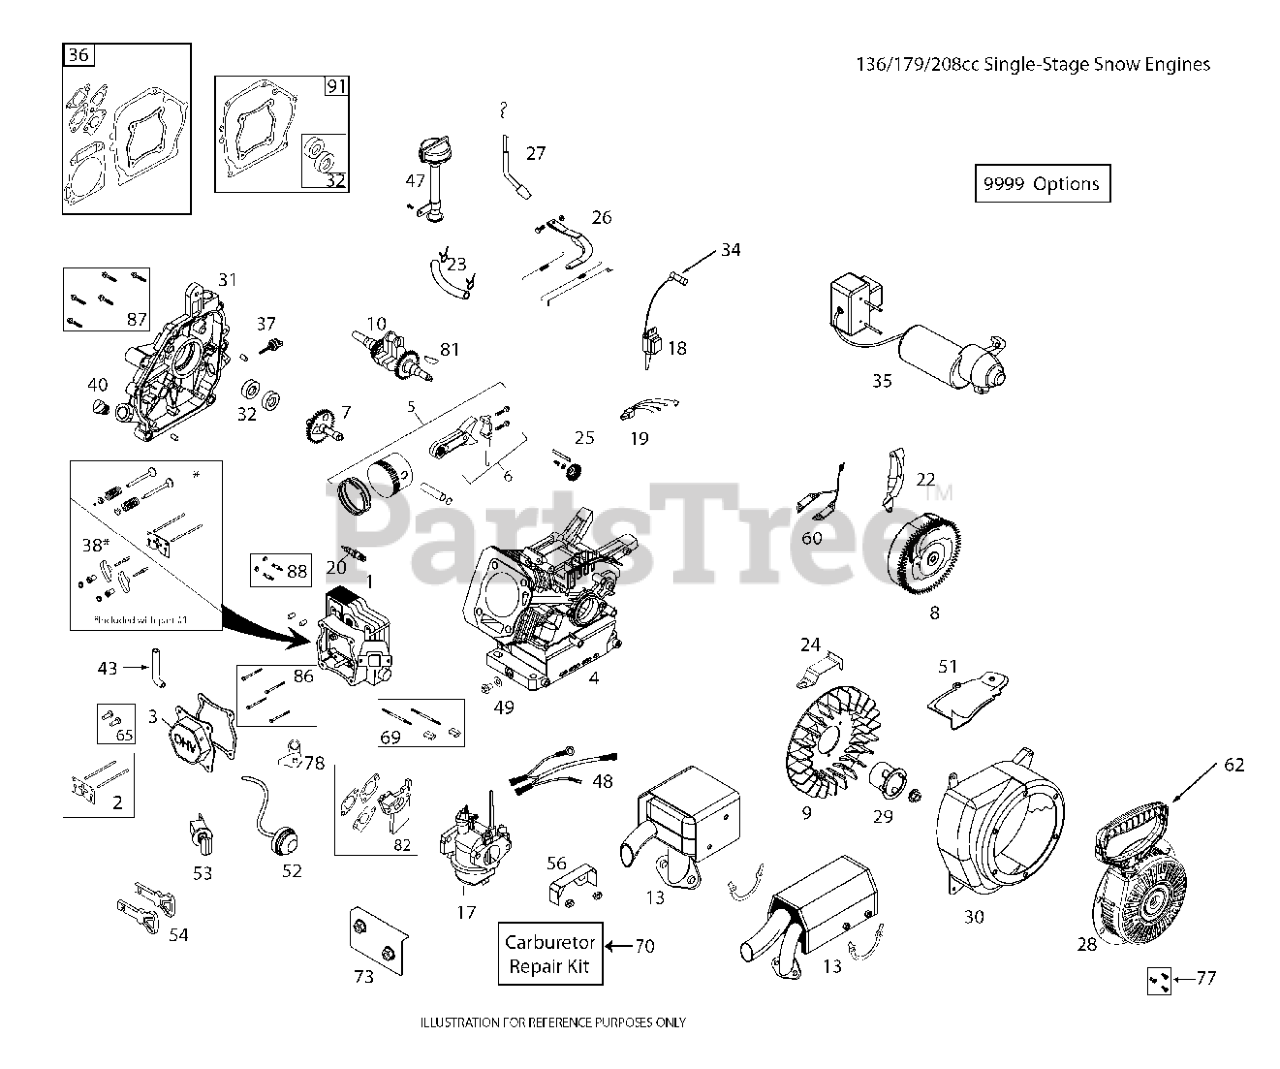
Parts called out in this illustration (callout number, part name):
4	PIPE COMPLETE
5	RP FUEL FILTER
7	TANK GUARD
